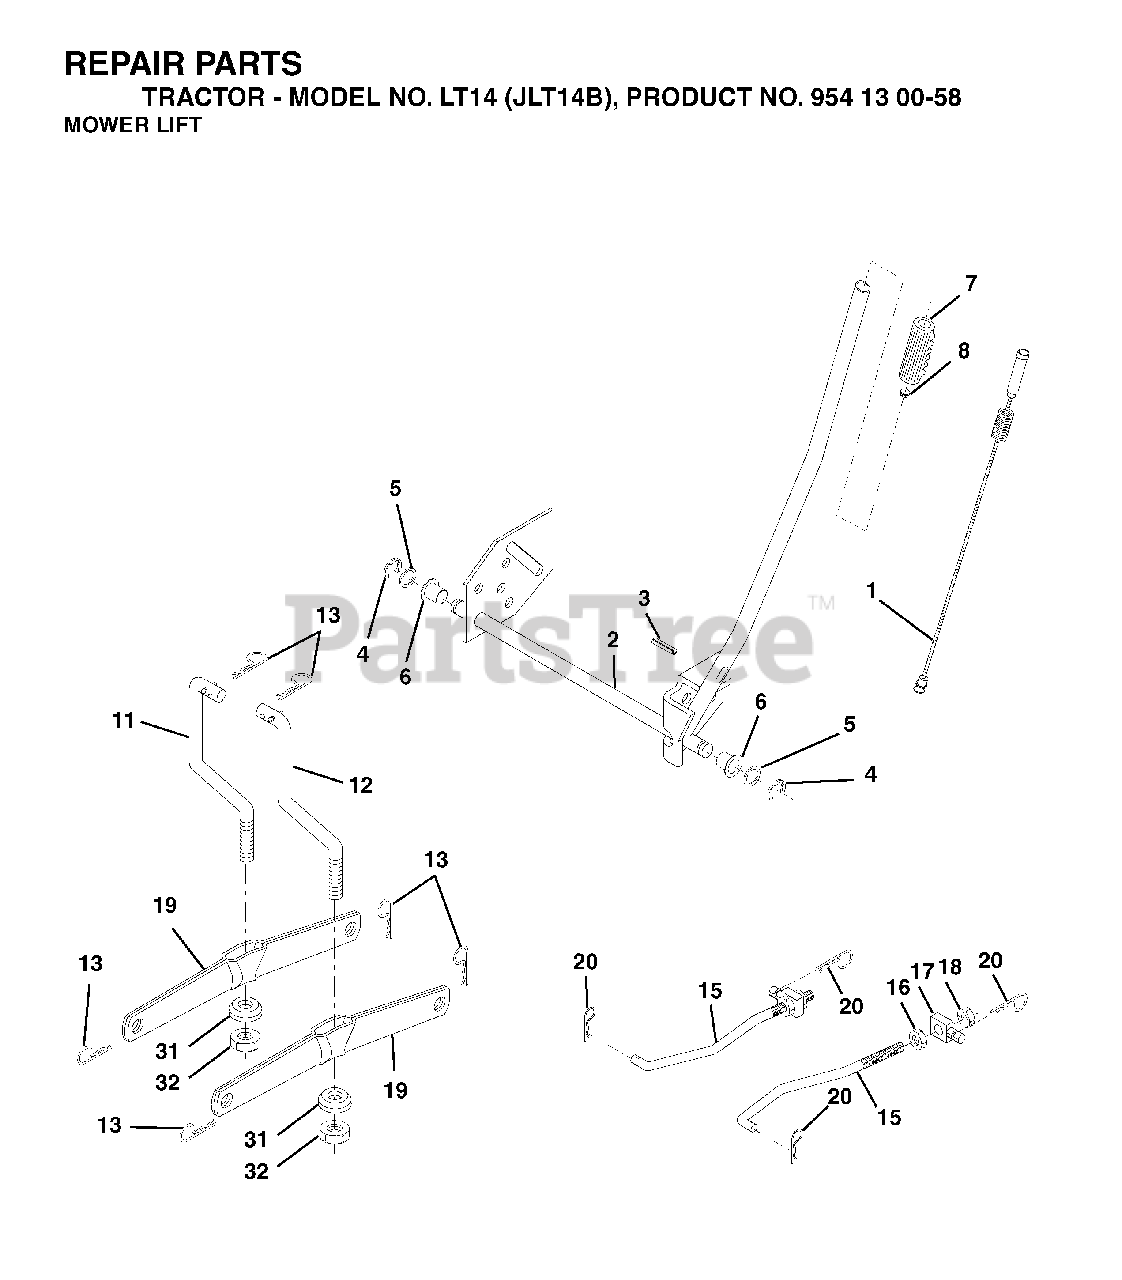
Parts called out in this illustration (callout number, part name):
1	WIRE ASM INNER W/ PLUNGER LT
2	SHAFT ASM R HANDLE
3	PIN GROOVE
4	RETAINING RING LT
6	BEARING.NYLON
7	GRIP
11	LINK LIFT LH
12	LINK LIFT RH
13	RETAINER-SPRNG RB
15	LINK.SUSPENSION.FRONT
16	NUT
18	NUT
19	ARM.REAR.SUSPENSION
20	SPRING RETAINER
31	BEARING.PIVOT.LIFT
32	NUT CROWNLOCK 3/8-24
